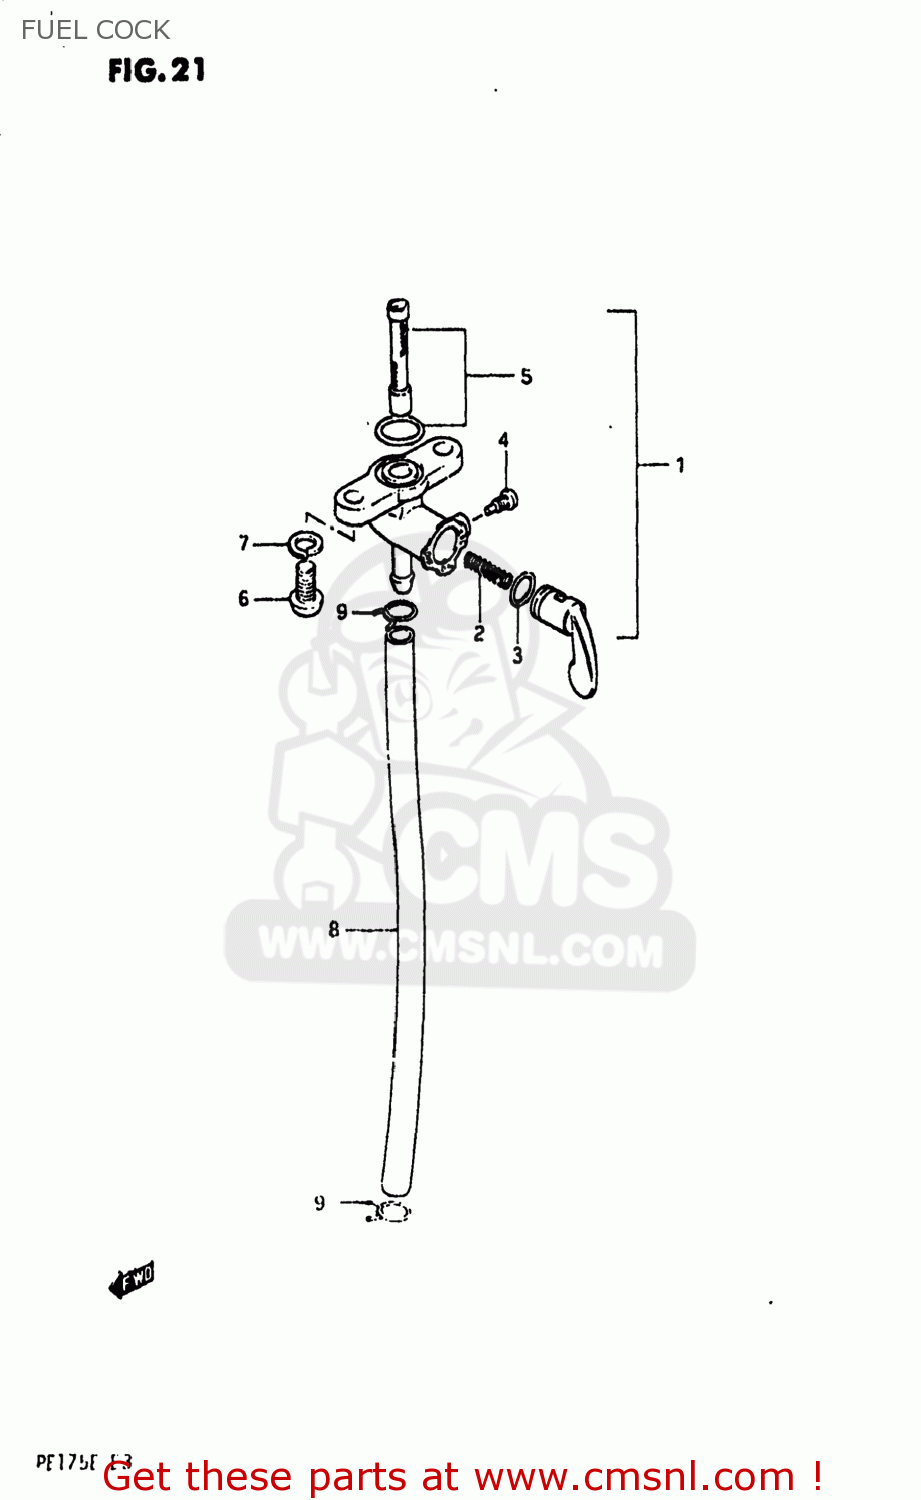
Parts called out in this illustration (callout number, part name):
1	COCK ASSY,FUEL
2	SPRING,FUEL COCK VALUE
3	O RING,LEVER
4	SCREW
5	FILTER SET FUEL
6	SCREW
7	LOCK WASHER
8	HOSE
9	CLAMP
